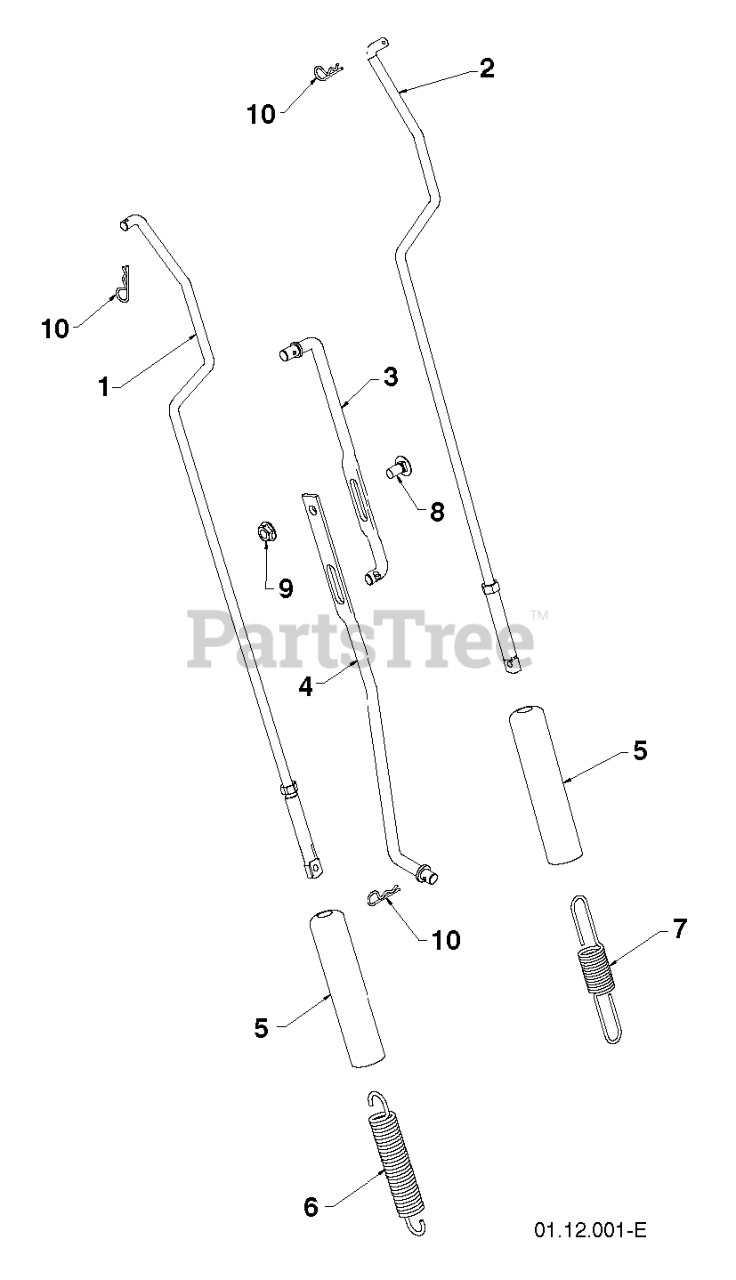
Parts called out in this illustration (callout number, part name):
1	ROD.ASM.IMPELLER
2	ROD.ASM.TRACTION
3	ROD, UPPER SPEED CONTROL
4	ROD, LOWER SPEED CONTROL.SNOW
5	SLEEVE, SPRING
6	SPRING, AUGER CONTROL
7	SPRING, TRACTION DRIVE
8	BOLT
9	NUT.FLANGE.5/16
10	SPRING RETAINER
